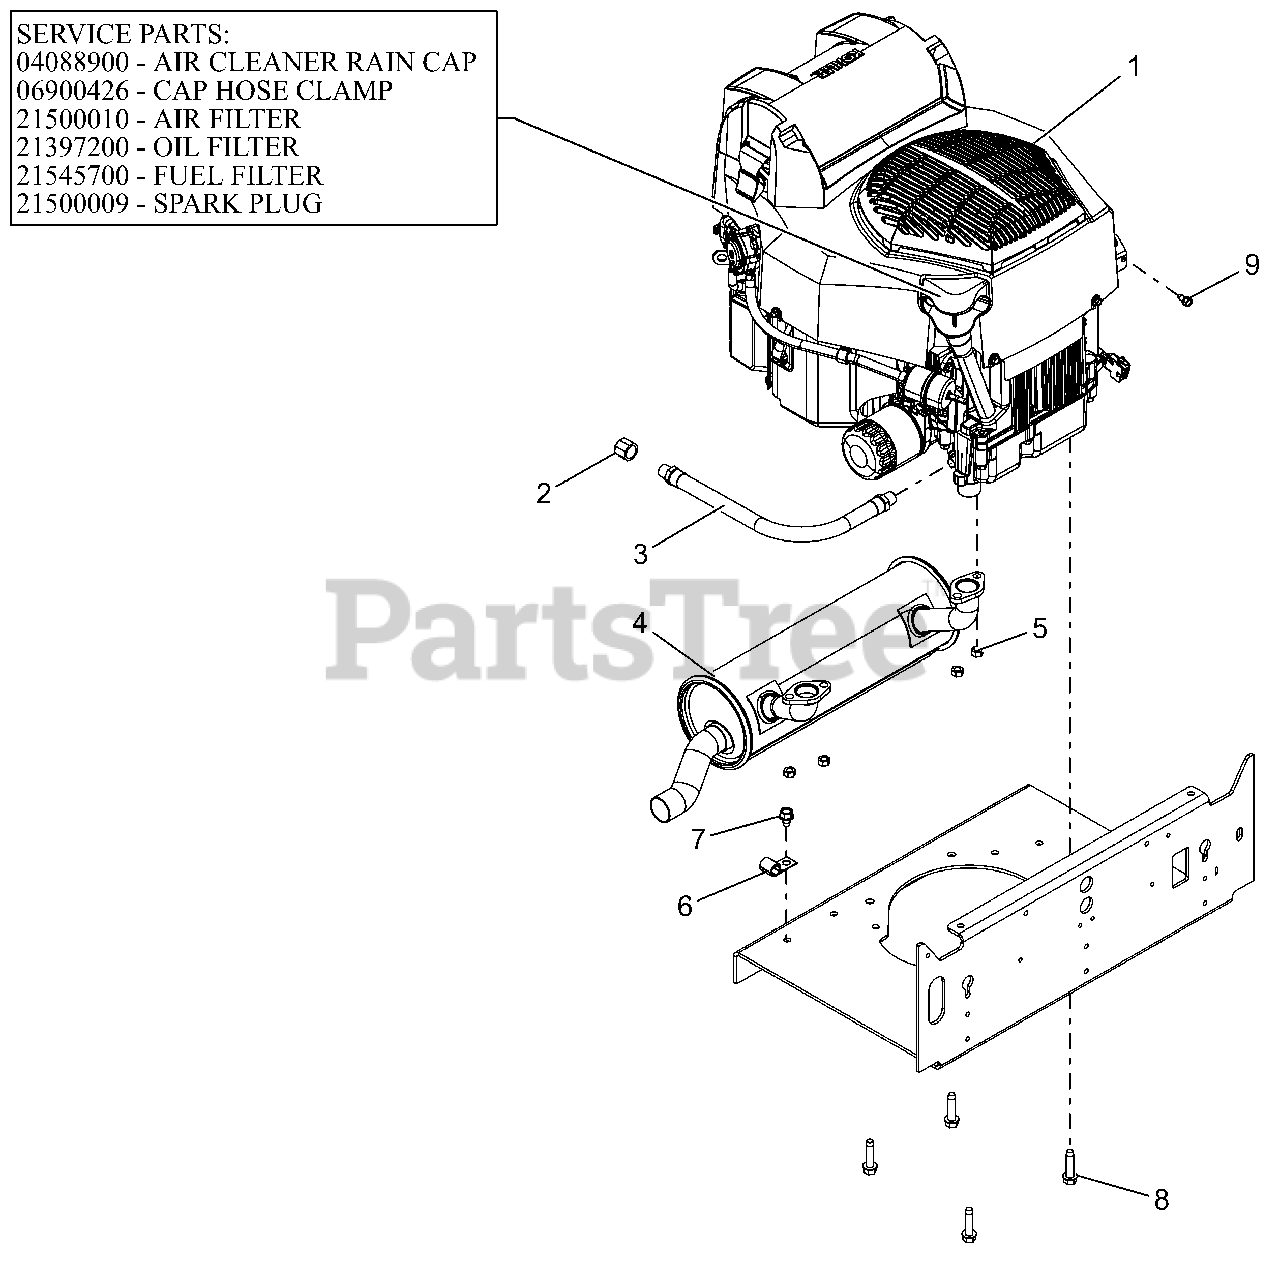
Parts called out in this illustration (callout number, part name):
1	ENGINE, KOHLER ZT730 CONFIDANT
1	CAP, KAW 11065-7025
1	CLAMP, HOSE #36 SS 1.813-2.75
1	AIR CLEANER, KOHLER CONFIDANT
1	FILTER, OIL - KOH CV20
1	FILTER-FUEL KOHLER COURAGE PRO
1	PLUG, SPARK KOHLER
2	PIPE CAP 3/8 NPT FEMALE
3	HOSE,HYD .38-14-0K M6N0-M6N0
4	MUFFLER, ZT730/ZT740
5	NUT-LK-TOP M8-1.25 YWZC
7	@SCR-TAP .38-16X.50 HWH TR YWZ
8	@SCR-TAP .38-16X1.50 HWH TR YZ
9	SCR-TAP .25-20X.50 HWH TR YWZ
